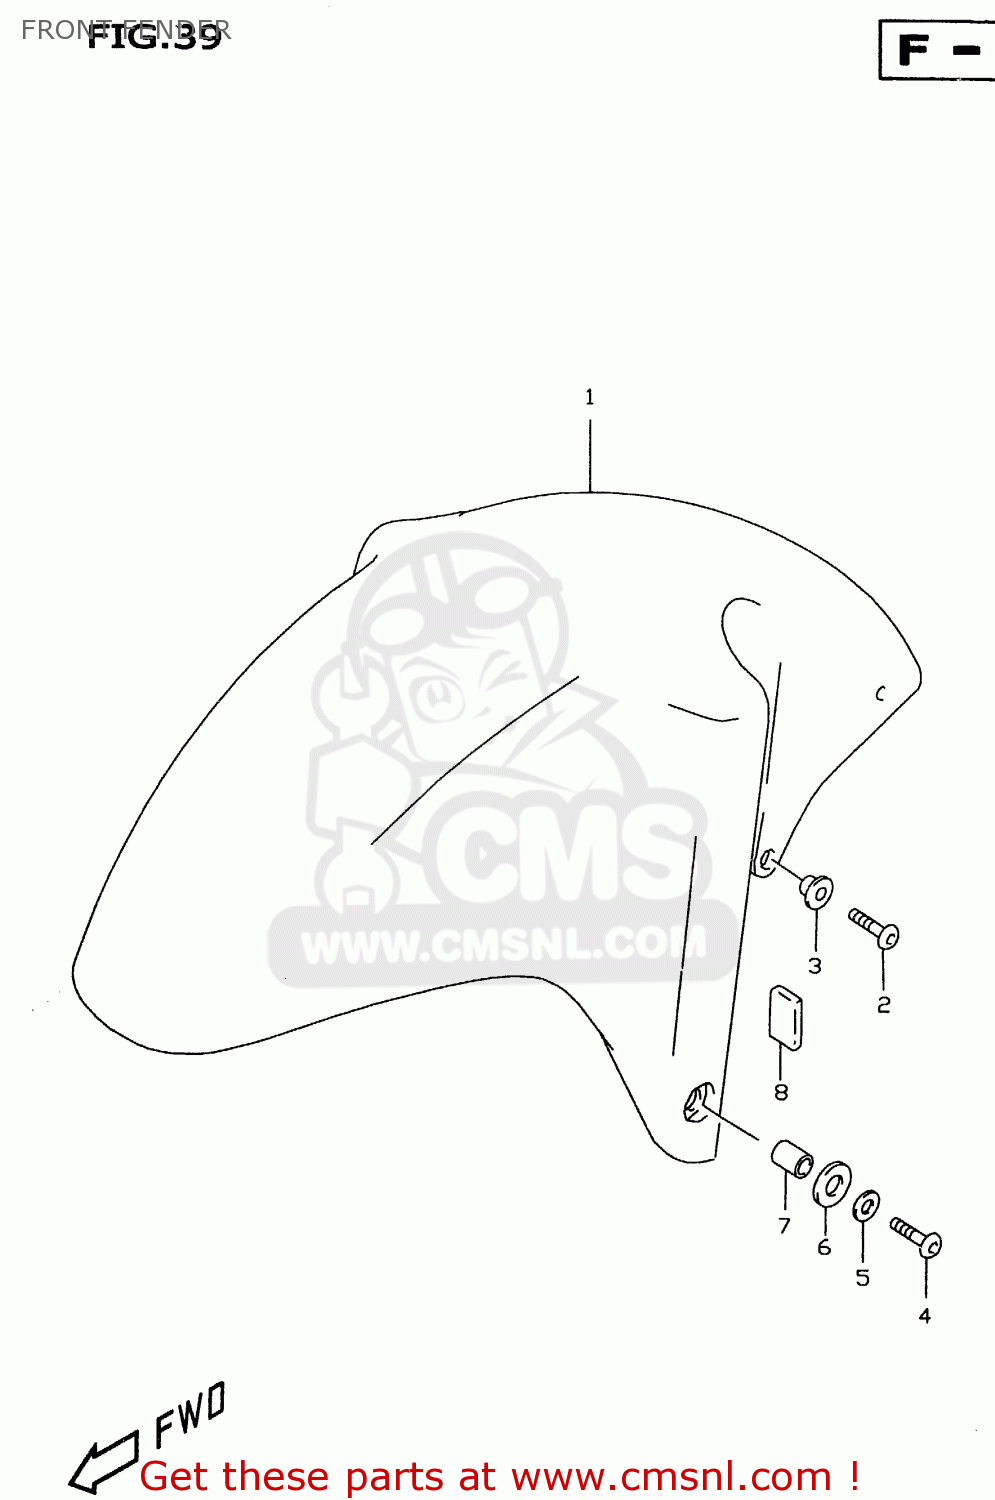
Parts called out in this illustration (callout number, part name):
1	FENDER,FR
2	SCREW(6X16)
3	WASHER(6.3X16X1.5)
4	SCREW(6X16)
5	WASHER(6.5X16X1.2)
6	WASHER,FR FENDER FR NO.2
7	SPACER(6.5X9X6.7)
8	CUSHION
